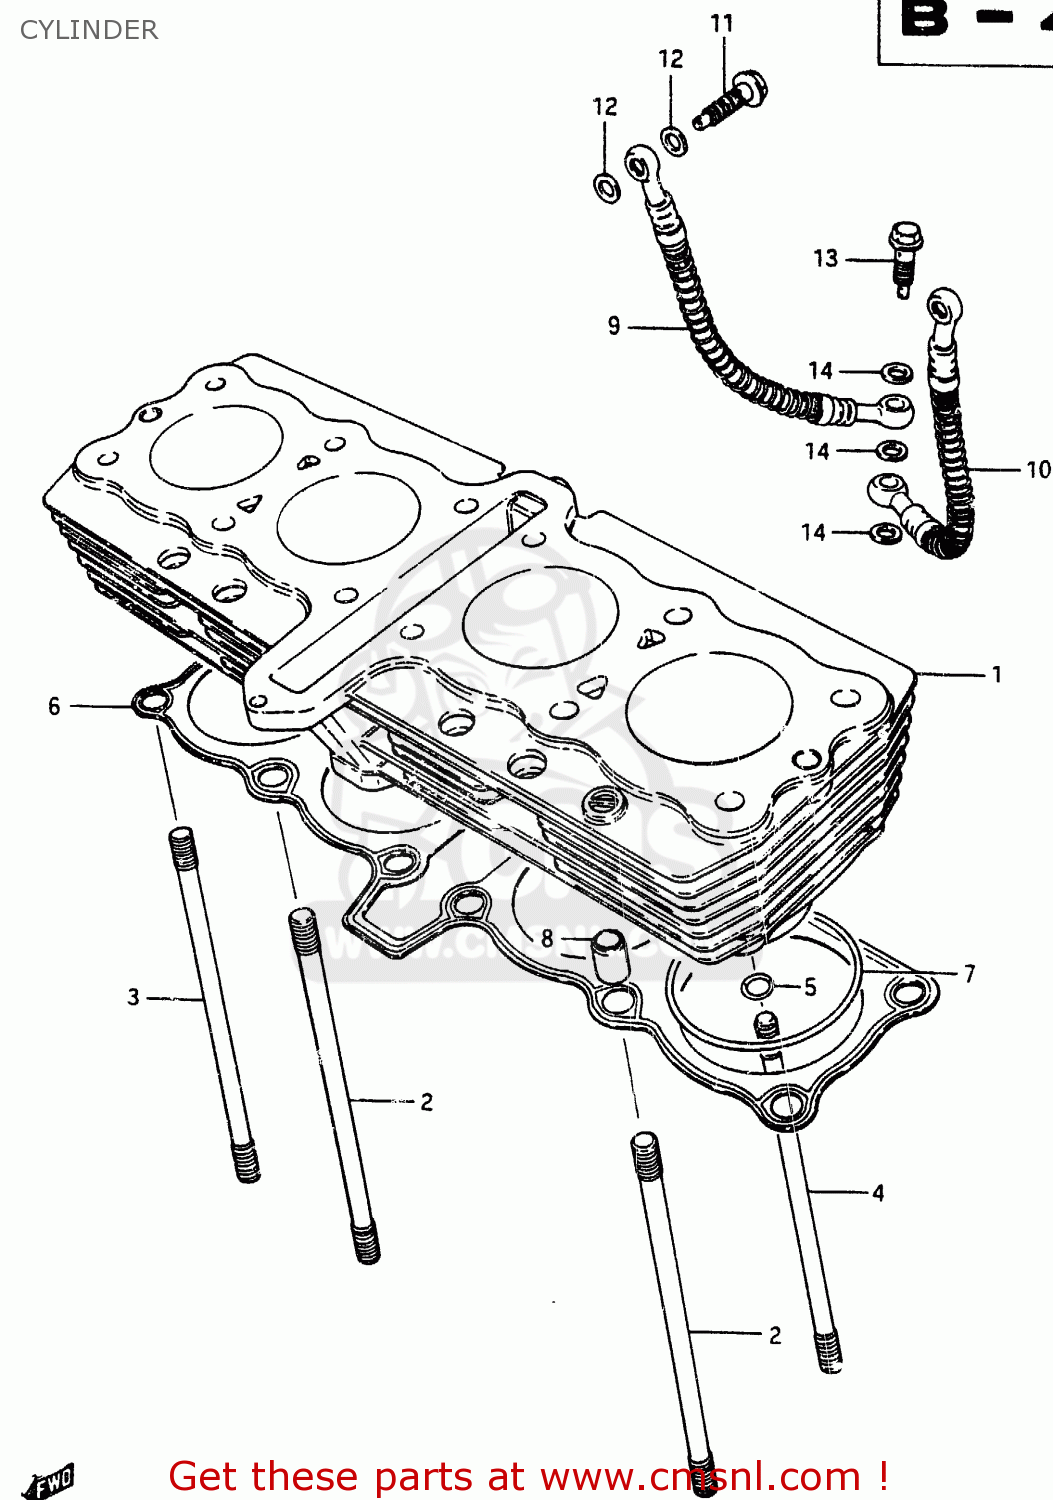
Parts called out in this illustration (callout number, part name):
1	CYLINDER
2	BOLT,STUD
3	STUD
4	STUD
5	O RING(D:2.4,ID:11)
6	GASKET,CYLINDER (NAS)
7	O RING(D:2,ID:70)
8	PIN
9	HOSE,OIL
10	HOSE,OIL
11	BOLT UNION
12	GASKET 8.2X14X1 (NAS)
13	BOLT,OIL PIPE
14	WASHER(10X15X1.5)
